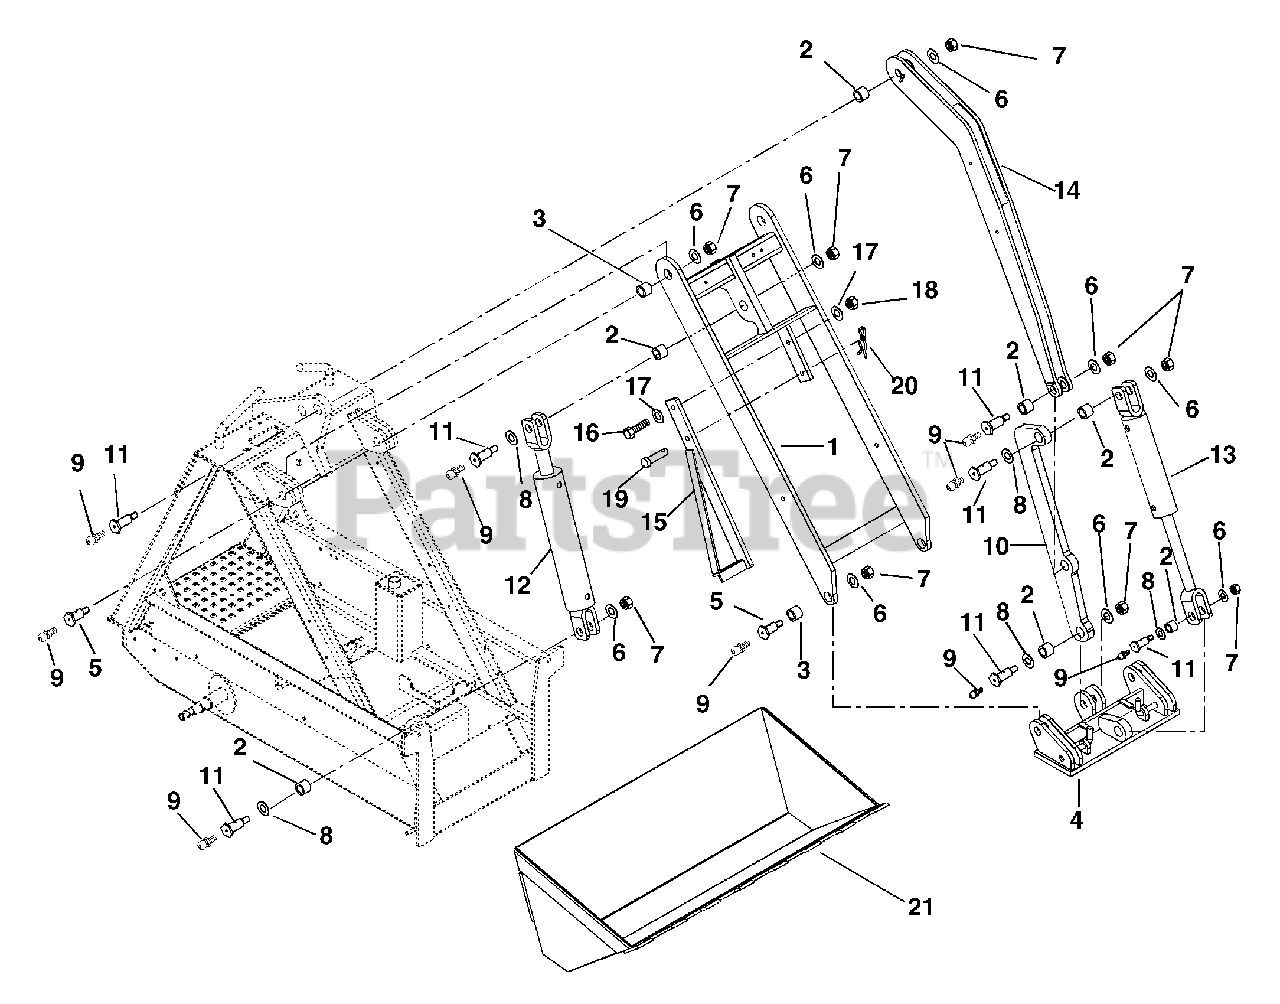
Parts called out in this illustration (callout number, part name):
1	Arm-Lift
2	Bushing-1.00 x 1.25 x 25.65 MM
3	Bushing-1.00 x 1.25 x 16.125 MM
4	Plate Attachment Weldment
5	Pin-Linkage "A" 1.50 Hex
6	Washer-Flat-Steel .656 x 1.31 x .095
7	Nut-Locking-Nylon M16-1.5
8	Washer-Flat-Steel 1.01 x 1.50 x .062
9	Fitting-Lube .25-28 x .256
10	Arm-Tilt
11	Pin-Linkage "B" 1.50 Hex
12	Cylinder-Lift
12	Seal, Replacement
13	Cylinder-Crowd
13	Seal, Replacement
14	Arm-Leveler
15	Bracket-Cylinder Lock Weldment
16	Bolt-Hex M12-1.75 x 45
17	Washer-Flat-Steel .531 x 1.06 x .095
18	Nut-Locking-Nylon M12-1.75
19	Pin-Clevis .438 x 1.50
20	Pin-Hair Internal .15 x 2.937
